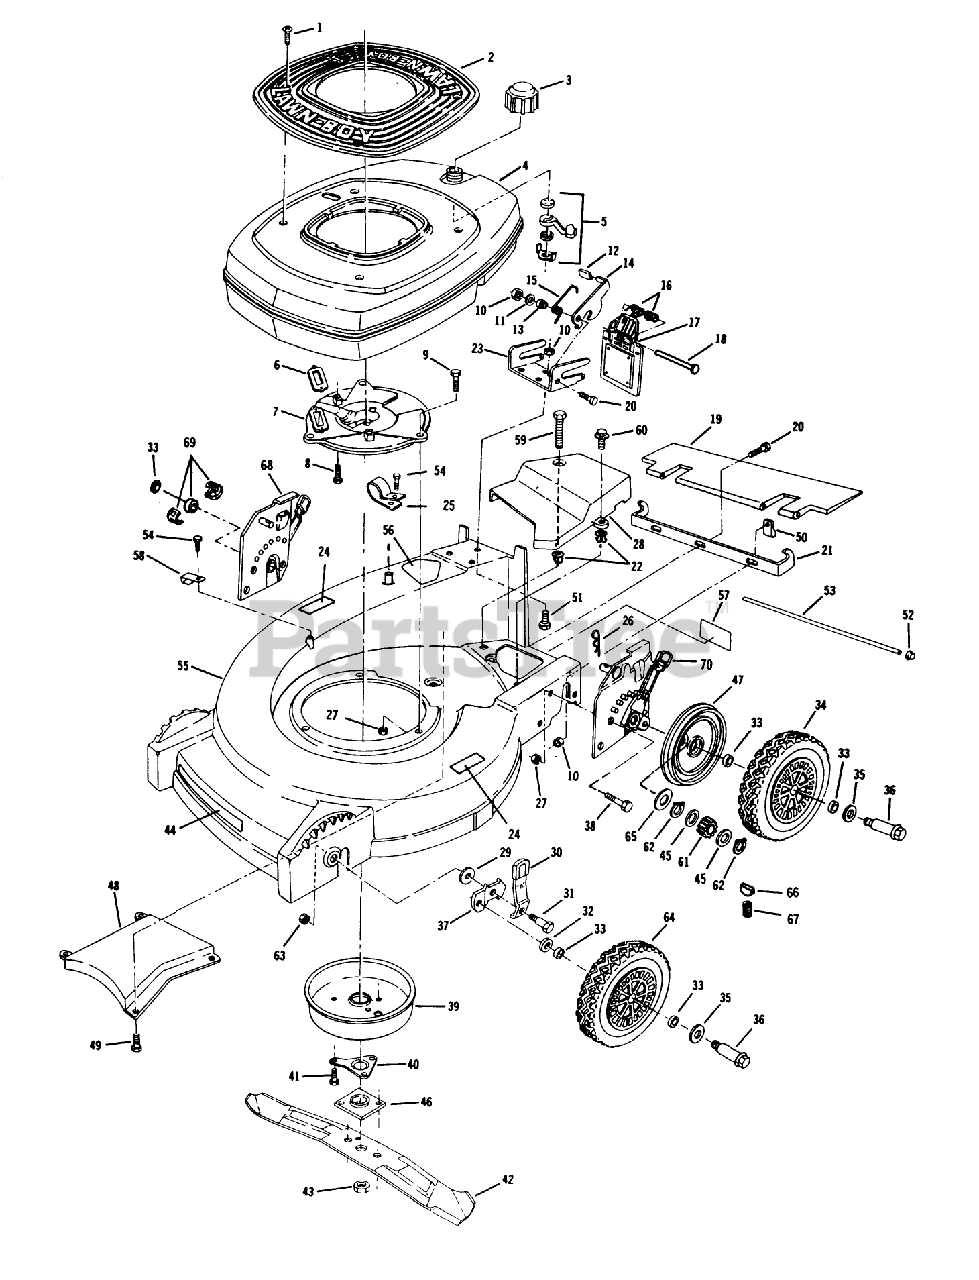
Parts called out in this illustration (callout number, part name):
1	SCREW - SELF TAPPING
3	FUEL CAP & INSERT
5	SHUT-OFF VALVE S
7	PLATE F
8	SCREW V
9	SCREW-HH
10	LOCKNUT E
15	SPRING
16	SPRING ASOC
18	ROD (RB&W)
19	T/SHIELD SM&P
26	HAIR PIN
27	NUT-LOCK F
29	WASHER
31	BOLT
32	WASHER WROUGHT
33	WASHER
35	SPACER
36	BOLT WHEEL
39	MUFFLER COVER F
40	SUPPORT F
41	SCREW
43	NUT-BLADE
45	SPACER/GR ALGHNY
46	PLATE AND COLLAR ASM
48	BAFFLE CHUTE PL
54	SCREW LAWRENCE
60	SCREW
61	PINION BROCKWAY
62	RET RING
63	LOCKNUT
64	WHEEL&TIRE 8" TRI
65	THRUST WASHER
66	KEY
67	SPRING
69	REAR AXLE BEARING
